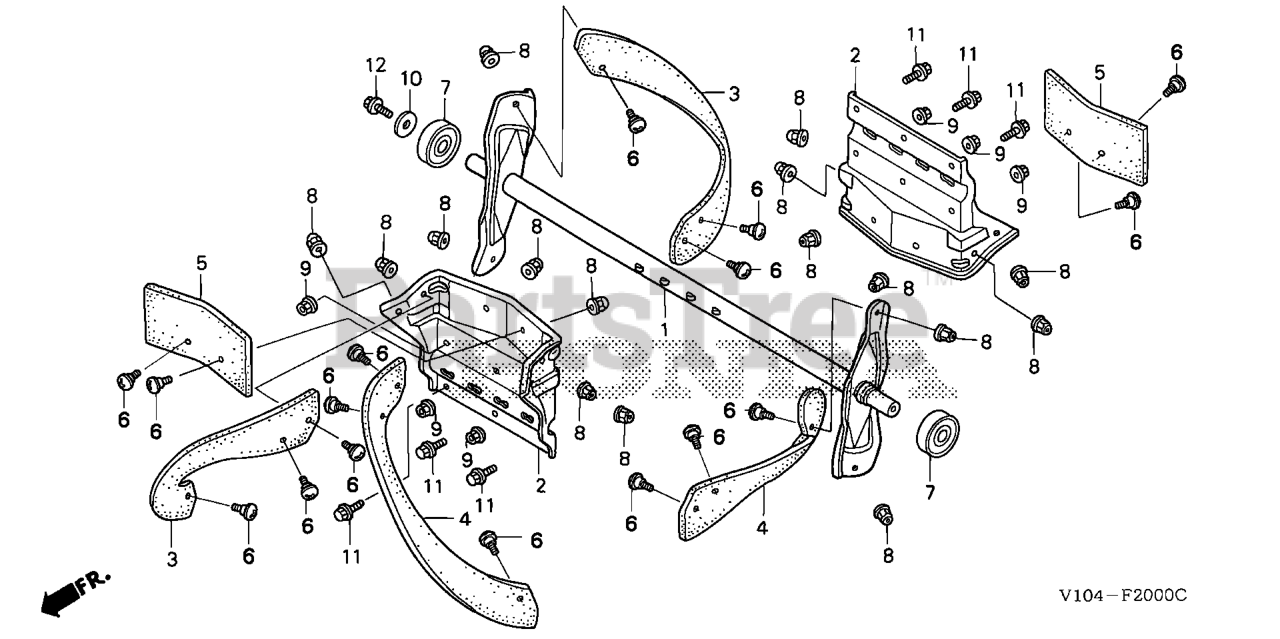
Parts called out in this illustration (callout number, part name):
2	PLATE, AUGER
3	RUBBER, R. AUGER
4	RUBBER, L. AUGER
5	RUBBER, BLOWER
6	BOLT, AUGER RUBBER
7	BEARING, RADIAL BALL (6203)
8	NUT, SELF-LOCK (6MM)
9	NUT, FLANGE (6MM)
10	WASHER, PLAIN (8MM)
11	BOLT, FLANGE (6X12) Use up to Engine SN 1543277.
12	BOLT, FLANGE (8X16) Use from Engine SN 1000016.
